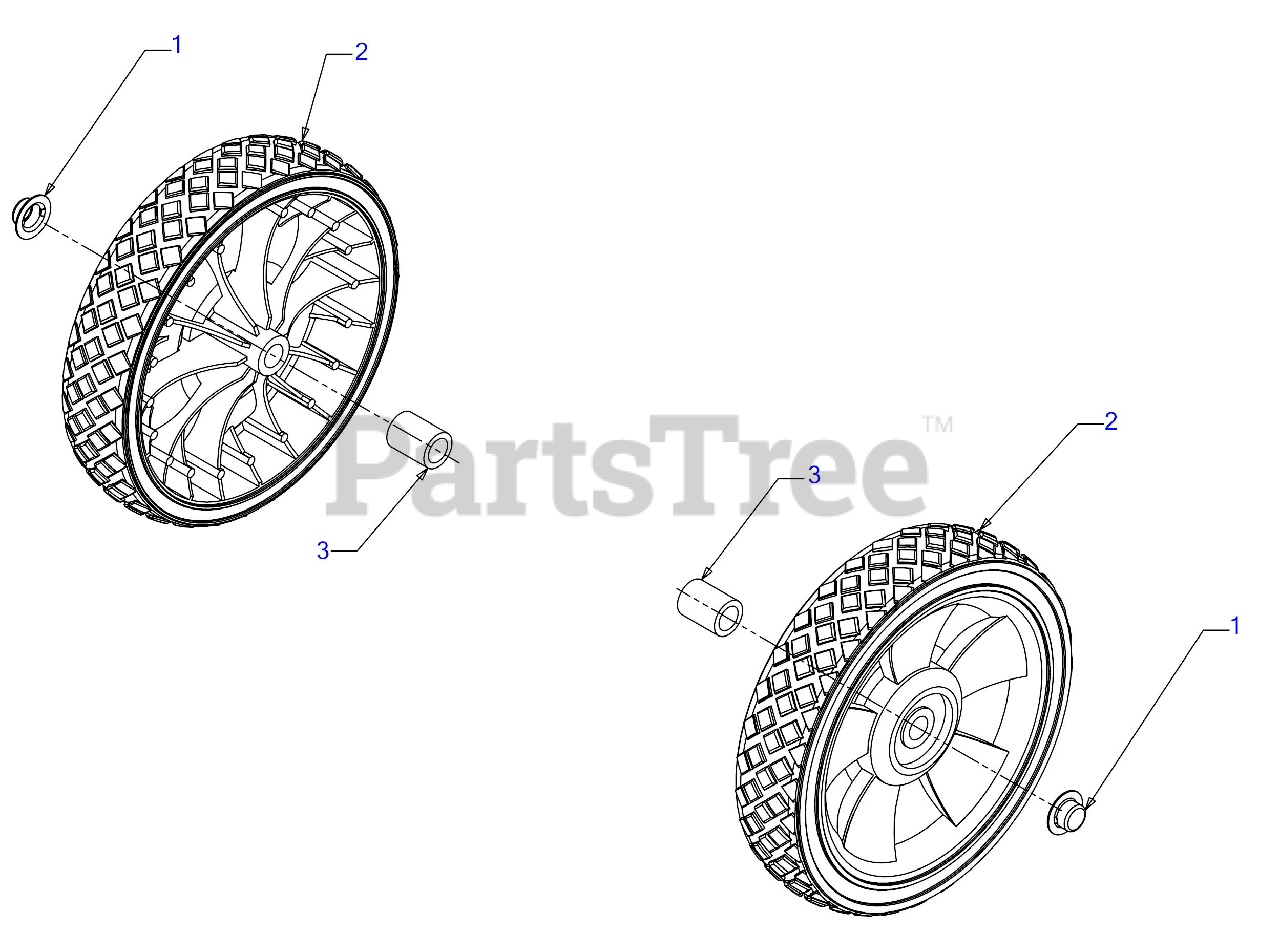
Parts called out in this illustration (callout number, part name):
1	PUSH CAP
2	COMPLETE WHEEL 8" GREY
3	SPACER .525 X .775 X 1.015
